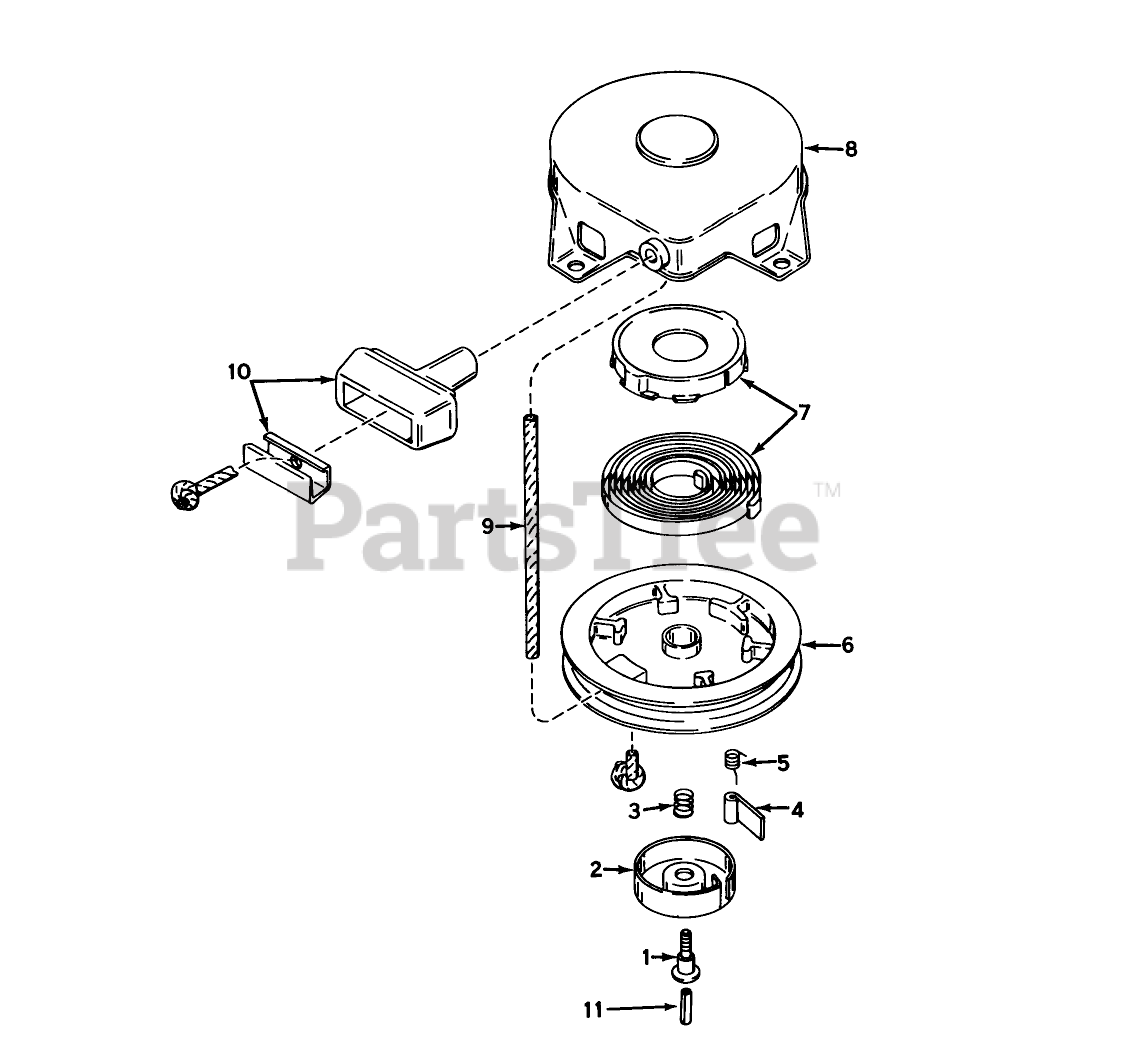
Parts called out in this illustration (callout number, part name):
1	Screw
2	Retainer
3	Spring-Brake
4	Dog-Starter
5	Spring-Dog
6	Pulley
7	Spring Keeper Assy
8	STARTER HOUSING ASSY
9	Rope Starter
10	Assy., Starter
11	Centering
